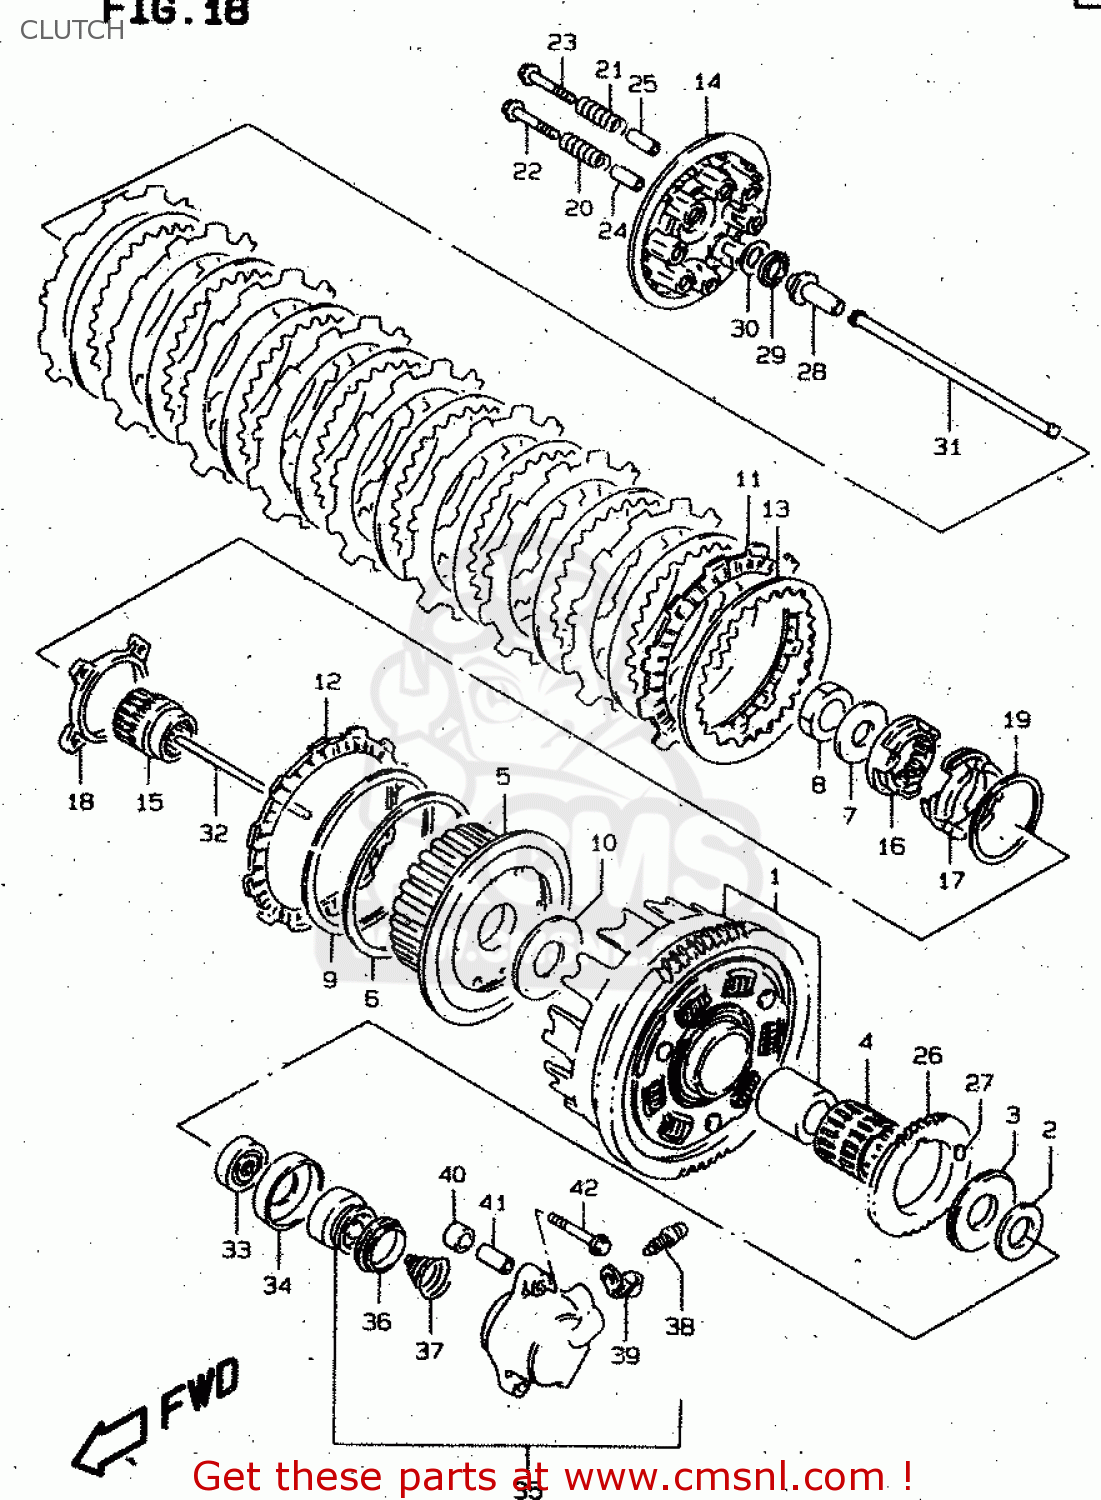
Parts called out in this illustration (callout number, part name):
1	GEAR ASSY,PRI DRIVEN
2	WASHER(25X38X2.5)
3	WASHER(25X54X2.5)
4	BEARING(35X40X35.8)
5	HUB,CLUTCH SLEEVE
6	SEAT,WAVE WASHER(T:1.4)
7	WASHER
8	NUT
9	WASHER
10	WASHER(25X60X2.5)
11	PLATE,CLUTCH DRIVE (NAS)
12	PLATE,CLUTCH DRIVE(T:3.5) (NAS)
13	PLATE,CLUTCH DRIVEN (NAS)
14	DISC,CLUTCH PRESSURE
15	SPACER,CLUTCH SLEEVE HUB
16	CAM,CLUTCH NO.1
17	CAM,CLUTCH NO.2
18	SLIDER,CLUTCH SPRING
19	WASHER(54X62X1)
20	SPRING
21	SPRING
22	BOLT(6X40)
23	BOLT
24	SPACER(6.4X10X22)
25	SPACER(6.5X9X24.1)
26	GEAR,OIL PUMP DRIVE
27	PIN(6X6)
28	PIECE,CLUTCH PUSH
29	BEARING(15X28X2)
30	WASHER(15.5X28X1)
31	ROD,CLUTCH PUSH,R
32	ROD,CLUTCH PUSH,L
33	SEAL,OIL(6X34X11)
34	RETAINER,CL PUSH ROD OIL SEAL
35	CYLINDER,CLUTCH RELEASE
36	CUP
37	SPRING,CLUTCH CYLINDER
38	BLEEDER
39	CAP,BLEEDER
40	SPACER(9X16X11)
41	PIN(6.4X9X23)
42	BOLT
